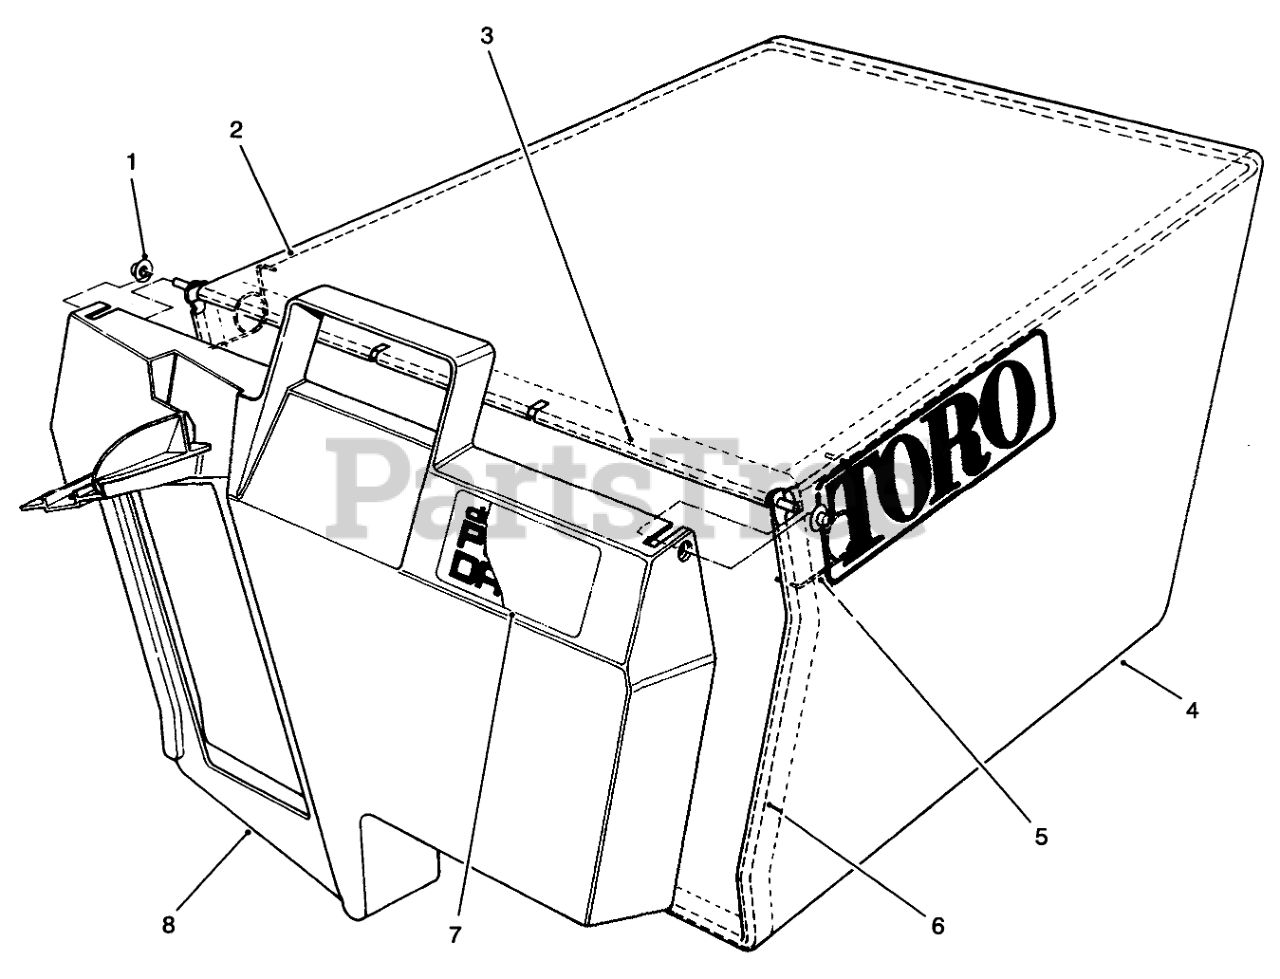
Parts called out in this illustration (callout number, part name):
1	NUT-PUSH
2	FRAME-BAG, UPPER
3	HINGE-DOOR, BAG
4	Bag
5	SPRING
6	FRAME-BAG
7	BAG DOOR DECAL
8	DOOR-BAG
